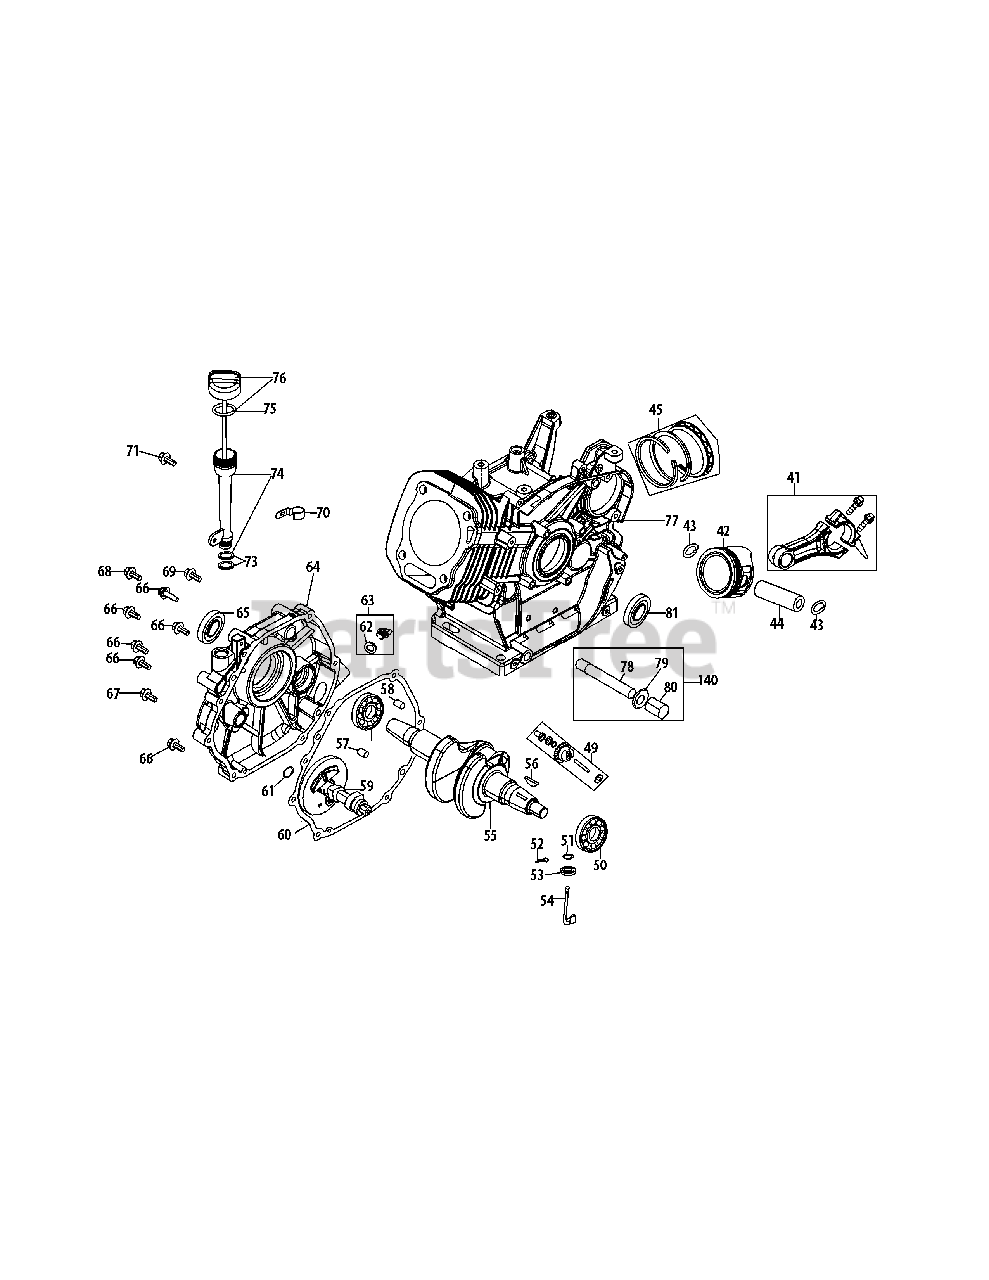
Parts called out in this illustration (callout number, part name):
41	Connecting Rod Assembly
43	Piston Pin Snap Ring
44	Piston Pin
45	Piston Ring Set
49	Governor Gear/Shaft Assembly
50	Radial Ball Bearing
51	Washer 8×20×0.8
52	Cotter Pin
53	Governor Seal
54	Governor Arm Shaft
55	Crankshaft Assembly
56	Woodruff Key
57	Dowel Pin 9×12
58	Dowel Pin 7×14
59	Camshaft Assy
60	Crankcase Cover Gasket
61	Washer 16x24×0.5
62	O-Ring 15.8×2.5
63	Oil Filler Plug Assembly
64	Cover Comp, Left Crankcase
65	Oil Seal 30×46×8
66	Bolt M8×38
67	Bolt M8×45
68	Bolt M8×35
69	Bolt M6×16
70	Dipstick Clamp
71	Bolt M6×8
73	Oil Fill Tube O-Ring
74	Oil Fill Tube Assembly
75	Dipstick O-Ring
76	Dipstick Assembly
77	Crankcase Kit
78	Oil Drain Pipe Assy.
79	Washer 10×16×1.5
80	Oil Drain Plug
81	Oil Seal 30x46×8
140	Oil Drain Assembly
